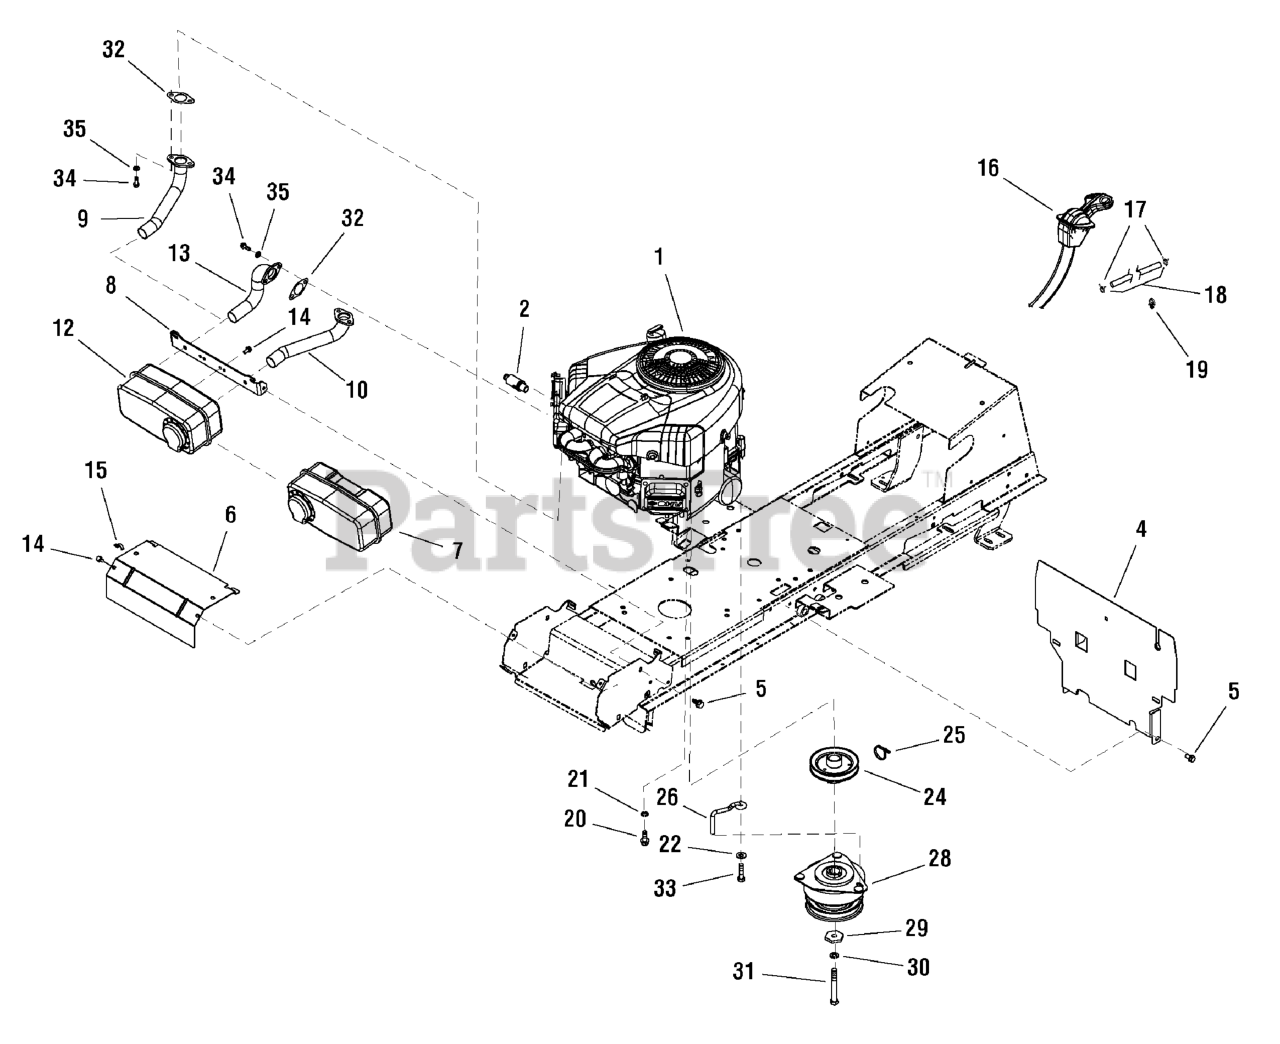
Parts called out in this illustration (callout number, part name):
1	ENGINE, 19.5HP B&S Intek Single
1	ENGINE, 22HP, B&S Intek Twin
2	VALVE, Shut Off Oil Drain
4	SHIELD, Heat
5	CAPSCREW, Hex Head, Taptite, 5/16-18 x 5/8
6	SHIELD, Heat
7	MUFFLER, B&S Twin
8	SUPPORT, Muffler
9	PIPE, Exhaust R.H.
10	PIPE, Exhaust L.H.
12	MUFFLER, B&S Single
13	PIPE, Exhaust
14	CAPSCREW, Hex Head, Taptite, 1/4-20 x 1/2
15	CLIP, Wire
16	THROTTLE CONTROL
16	CONTROL, Throttle Twin
17	Clamp, Hose UM5008
18	Hose, Fuel 1-9920-247
19	CLIP, Hose
20	SCREW, Hex Washer Head Taptite 3/8-16 x 1
21	LOCKWASHER, External Tooth, 3/8
22	WASHER, 3/8
24	PULLEY & HUB ASSEMBLY, Engine
26	RETAINER, Clutch
28	CLUTCH, Electric (LONG OGURA)
29	WASHER, Hex, 7/16, Black
30	LOCKWASHER, 7/16
31	CAPSCREW, Hex Head 7/16-20 x 3-1/2 G5
32	GASKET, Exhaust
33	SCREW, Hex Washer Head Taptite 3/8-16 x 1-1/4
34	CAPSCREW, Hex Socket Head 5/16-18 x 3/4 G8
35	LOCKWASHER, 5/16
